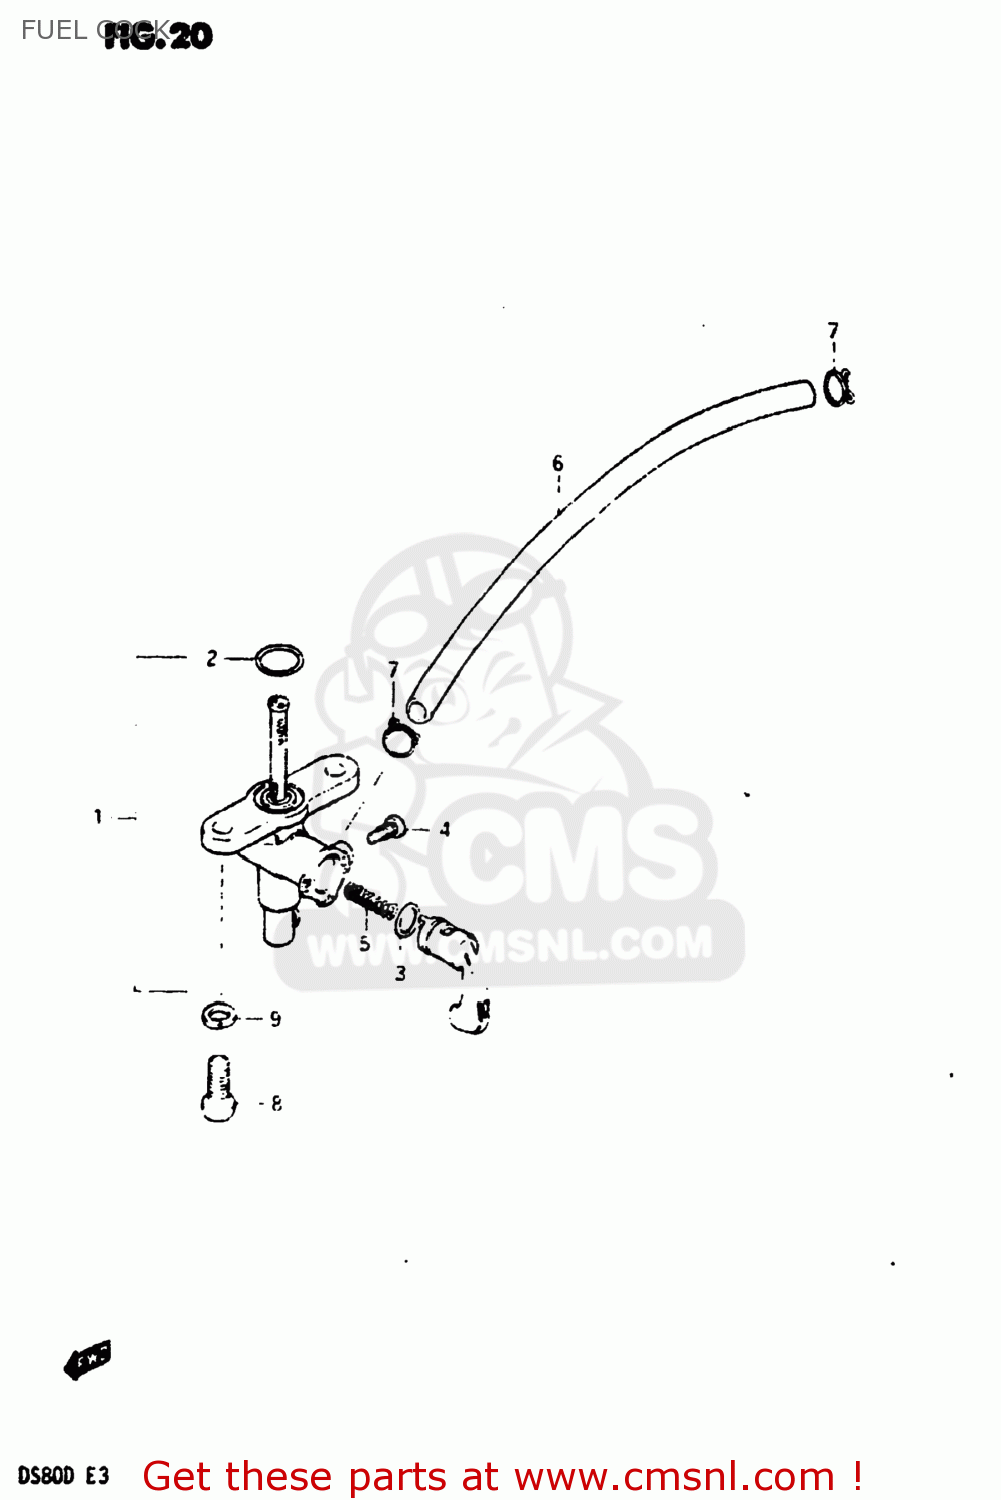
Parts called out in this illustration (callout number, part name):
1	COCK ASSY,FUEL
2	O RING
3	O RING,LEVER
4	SCREW
5	SPRING,FUEL COCK VALUE
6	HOSE
7	CLIP
8	SCREW
9	LOCK WASHER
